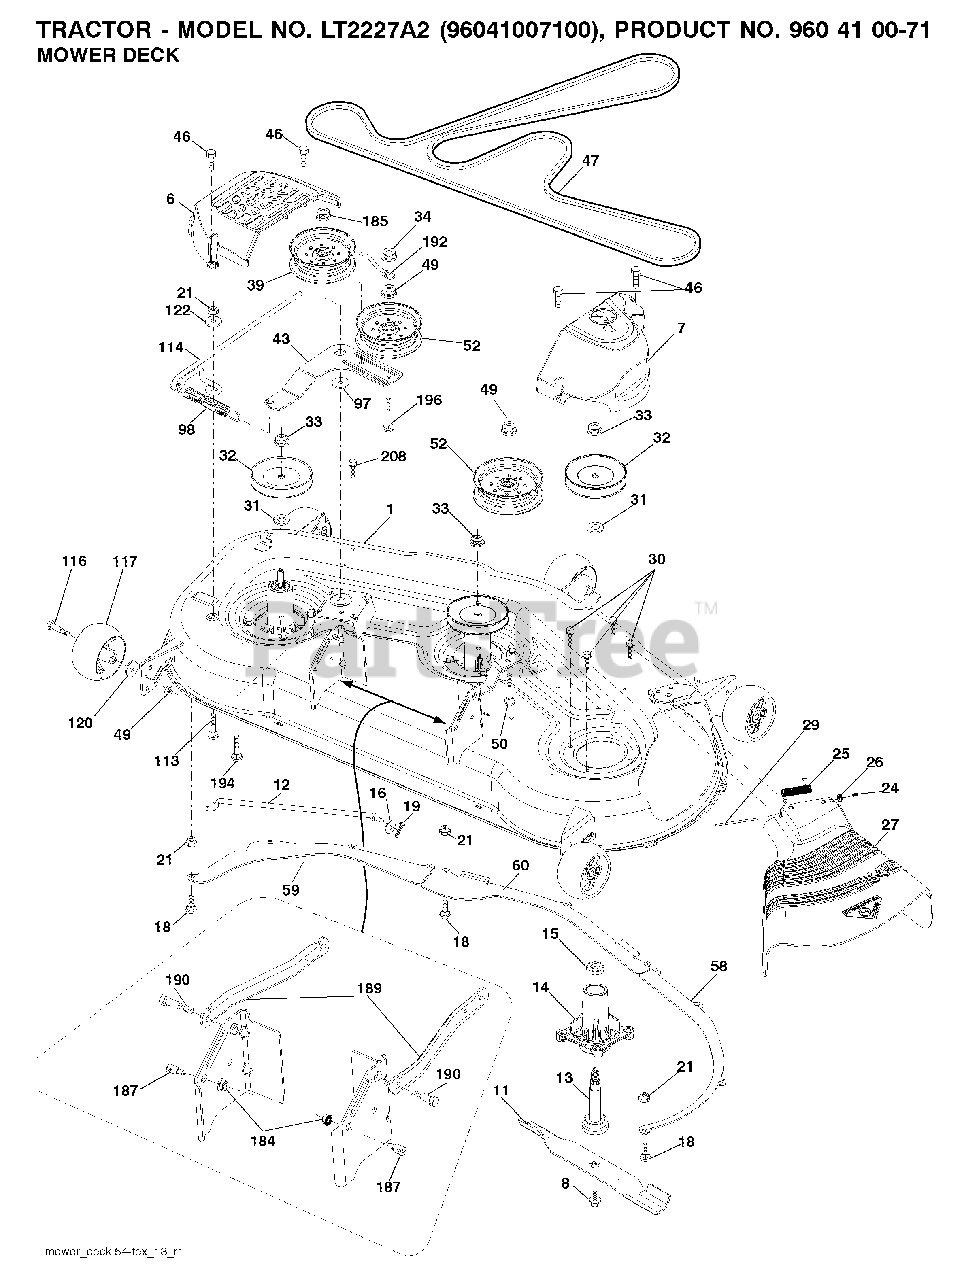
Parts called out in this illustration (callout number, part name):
1	DECK.WELDMENT.54'
6	COVER.MANDREL.LH.54"20
7	COVER.MANDREL.RH.54.20
8	BOLT 7/16 ASM BLADE
11	BLADE, BAGGING 54"
12	ROD.ANTI.SWAY.48/54"TE
13	SHAFT ASM MANDREL
14	HOUSING MANDREL
16	WASHER
18	BOLT
19	PIN.COTTER.5/16.BOW TI
21	LOCKNUT
24	CAP-SLEEVE LT
25	SPRING, TORSION
26	NUT PUSH M
27	DEFLECTOR
29	ROD.HINGE
30	SCREW, WASHER HEAD
31	WASHER.SPACER.MANDREL
32	PULLEY/MANDREL
33	NUT.FLANGE.LOCK.TOP
34	LOCKNUT
39	PULLEY.IDLER.4.50/HUB SPECIAL
43	ARM.IDLER
46	SCREW.1/4-20X5/8
47	BELT.DRIVE.54."2006
49	NUT LOCK FLG 3/8-16 UNC
50	BOLT
52	PULLEY.IDLER.2006
58	BAFFLE.RIGHT.54"
59	BAFFLE.LEFT.54"
60	BAFFLE CENTER 54" MOWER
98	SPRING, DECK DRIVE
114	ROD TENSION RELIEF
116	BOLT.SHOULDER.3/8-16X3-5/8
117	WHEEL. GUAGE RALLY
122	BUSHING.RELIEF.TENSION
184	NUT LOCK HEX FLANGE 5/16-18
185	NUT.LOCK.FLANGE.7/16
187	STUD.FASTNER.W/ANTI-ROTATE
189	ARM.SUSPENSION.MOWER
190	BOLT.SHOULDER
192	KEEPER.BELT.IDLER.54"T
194	BOLT.CARR.SQNK.7/16
196	BOLT
208	SCREW 3/8-16X1/2
